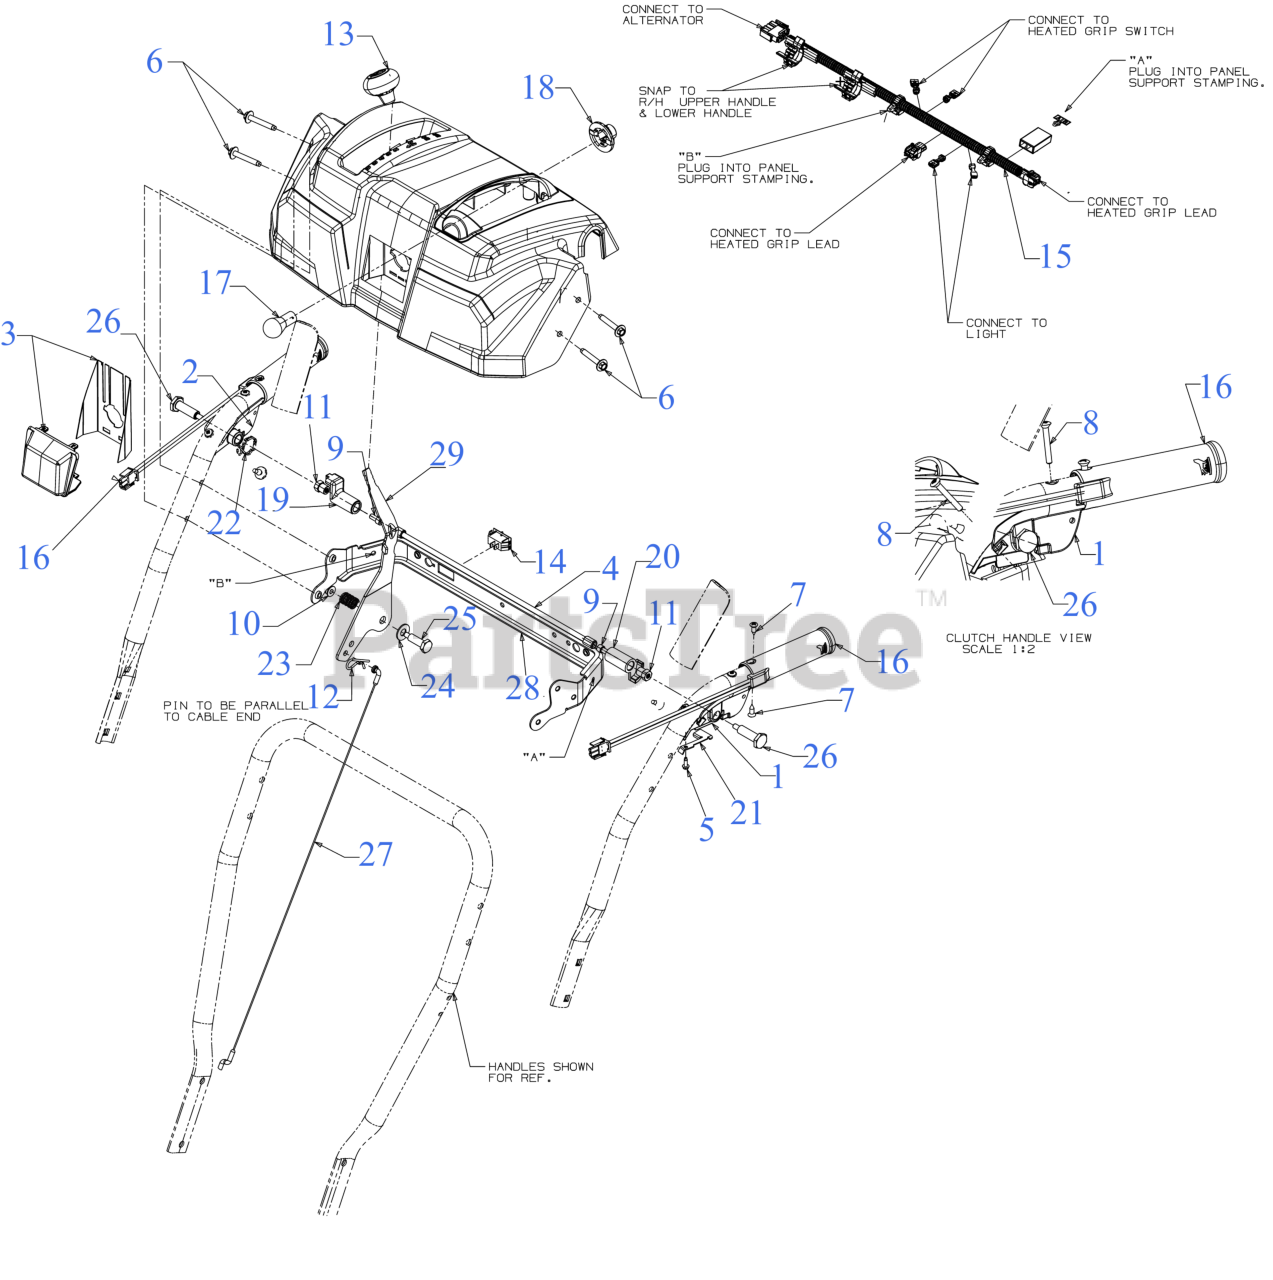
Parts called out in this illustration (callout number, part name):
1	CLUTCH LOCK HANDLE ASSEMBLY (LH)
2	CLUTCH LOCK HANDLE ASSEMBLY (RH)
3	HANDLE PANEL ASSEMBLY
3	LABEL:SNOW:2 STAGE
5	SCREW #8-16 x .50
6	SCREW 1/4-20 x 1.625
7	SCREW-AB #12-24 x .625
8	SCREW #10-24 x 1.375
9	SCREW 1/4-20 x .50
10	FLANGE LOCK NUT
11	HEX NUT W/PATCH
12	INTERNAL COTTER PIN
13	SHIFT KNOB
14	HEATED GRIP SWITCH
15	HEATED GRIPS HARNESS
16	HEATED GRIP
17	LAMP-12 VOLT
18	HEADLIGHT SOCKET (1/4 TURN)
20	CLUTCH LOCK CAM
21	CLUTCH SPRING
22	TORSION SPRING
23	COMPRESSION SPRING
24	FLAT WASHER
25	SHOULDER SCREW
26	SHOULDER SCREW .437 x 1.345 1/4-20
27	SPEED SELECTOR CABLE (PLASTIC)
